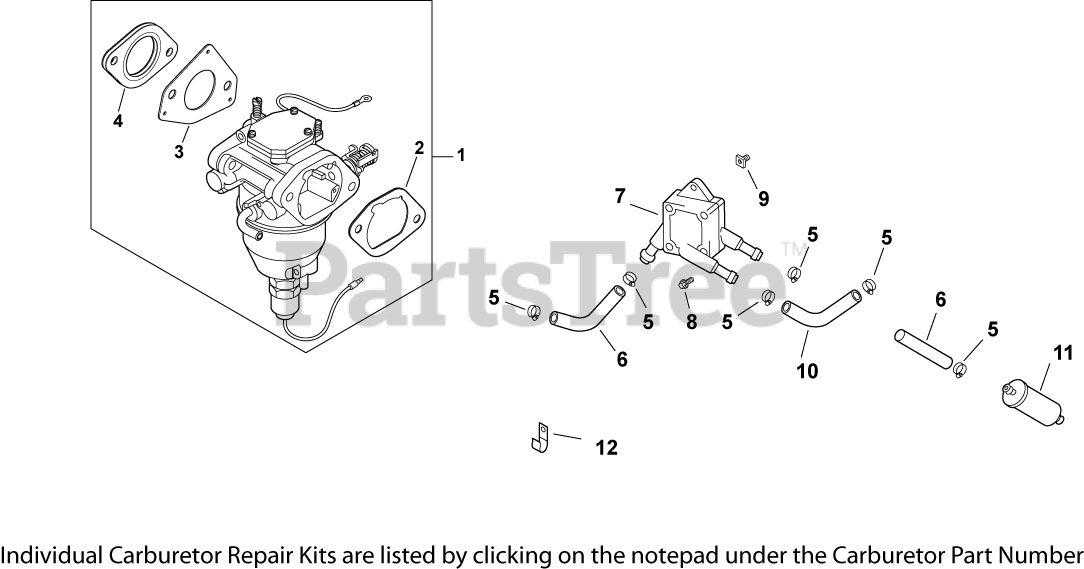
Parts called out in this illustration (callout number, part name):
1	CARBURETOR KIT-USE 24 853 171-S
2	GASKET, AIR CLEANER BASE
3	GASKET, CARBURETOR
4	GASKET, CARBURETOR
5	CLAMP, HOSE (KM)-USE 25 237 31-S
6	HOSE,LW PERM.FUEL 24.00"-USE 25 111 81-S
7	PUMP, FUEL
8	SCREW, TAP M6X1.7X18
9	NUT, PLASTIC - BLACK
10	LINE, FUEL 11"
11	FILTER,FUEL 51 MICRON (FUEL PUMP)
12	CLIP, CABLE
